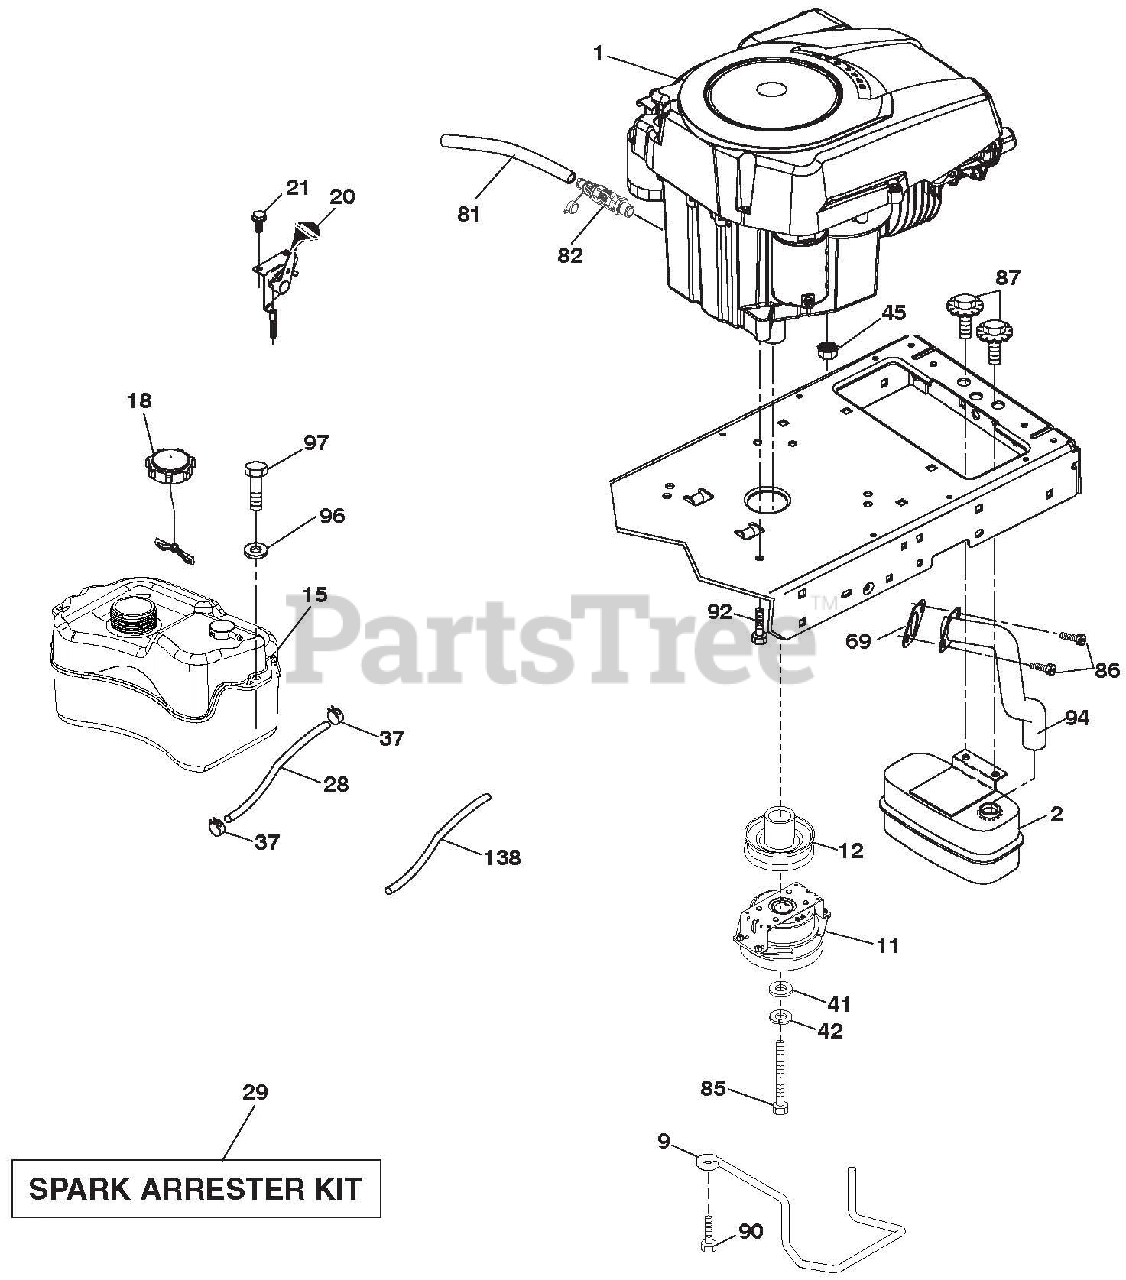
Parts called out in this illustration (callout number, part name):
2	MUFFLER
9	KEEPER.BELT.ENGINE
11	ELECT. CLUTCH
12	PULLEY.ENGINE.TUFFTORQE.1"CRK.
15	TANK.FUEL.2.5.GAL.
18	CAP.FUEL
20	CONTROL THROTTLE/CHOKE
28	LINE.FUEL.22"FRONT.EMIS.CA.LP
29	KIT.SPARK ARRESTOR(392390 B&S)
37	CLAMP.HOSE.BLK.
41	WASHER.1-1/2 ODX15/32 IDX.250
42	WASHER.LOCK.HVY HLCL.SPR.7/16
45	Nut, Keps Hex 1/4-20 unc
69	GASKET.KOHLER.SV.I.
81	TUBE.DRAIN.OIL.EASY
82	VALVE OIL DRAIN
86	SCREW SOCKET HEAD 5/16-18 X 1
87	BOLT.5/16-18UNCX3/4 W/SEMS.BLK
90	SCREW.3/8-16X1.SMGML.TAP/R.BLK
92	SCREW.3/8-16 X 1.SMGML.TAP/R
94	TUBE.EXHAUST (ENGINE)
96	WASHER.9/32 X 7/8 X 16GA.
97	SCREW.HEXWSH.THDROL.1/4-20X3/4
138	PURGE.LINE.CARB
